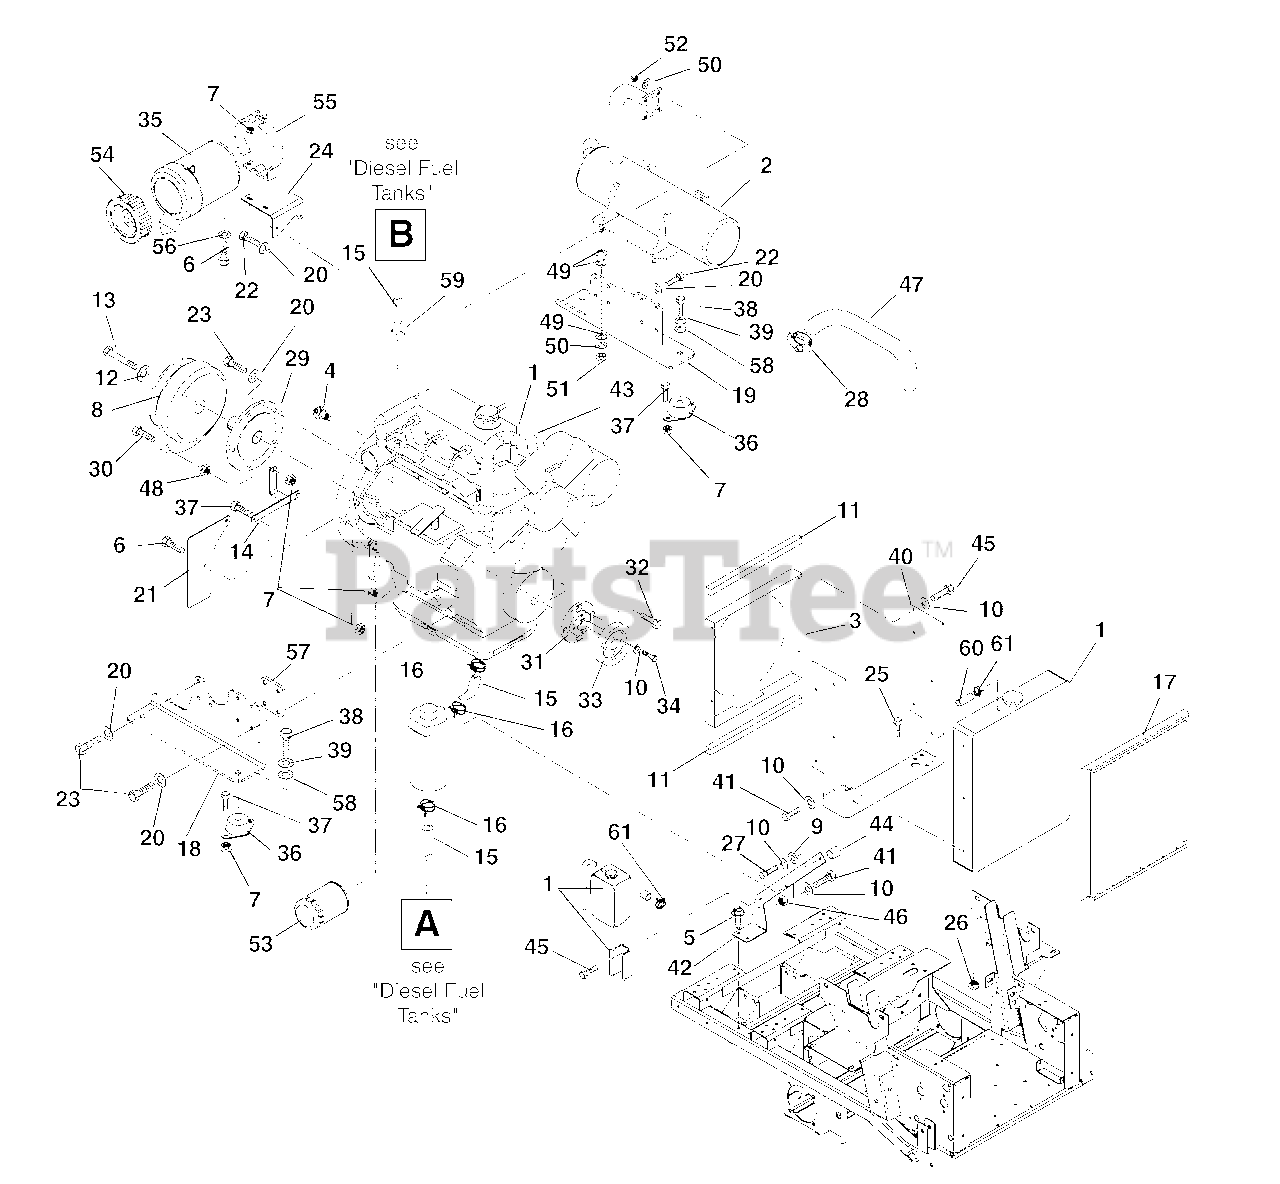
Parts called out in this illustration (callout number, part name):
1	Engine, 31HP Diesel (Daihatsu)
3	Weldment, Radiator Shroud
4	Sender, Temperature
5	Screw-Tapping .38-16 x .75 Hex Washer Head
6	Bolt-Hex .31-18 x .75 Grade 5
7	Nut-Locking-Nylon .31-18
8	Electric Clutch
9	Washer-Flat-Steel .281 x .62 x .065
10	Washer-Locking .25 x .062 Regular
11	Seal, Trim-LOK Bulk .06 Bubble
12	Washer-Locking .44 x .109
13	Bolt-Hex .44-20 x 2.50 Grade 5
14	Stabilizer, Clutch
15	Gas Line-Bulk .31" ID
16	Hose-Clamp
17	Screen, Radiator (Diesel)
18	Mount, Engine Right Hand (Diesel)
19	Mount, Engine Left Hand (Diesel)
20	Washer-Lock .31 x .078 Regular
21	Guard, Flywheel
22	Bolt-Hex M8-1.25 x 20
23	Bolt-Hex M8 x 1.25 x 25 Grade 8
24	Bracket, Air Cleaner
25	Bolt-Hex .38-16 x 1.00 Grade 5
26	Nut-Locking-Nylon .38-16
27	Bolt, Hex M6-1.00 x 45
28	Clamp, 2.25 Dia. Hose
29	Weldment, Stub Shaft
30	Bolt-Hex .31-18 x 1.50 Grade 5
31	Adapter, Sheave (Diesel)
32	Bolt, M8-1.25X25
33	Sheave 3.50
34	Bolt-Hex .25-20 x .50 Grade 5
35	Assembly, Air Cleaner
36	Mount, Engine
37	Bolt-Hex .31-18 x 1.00 Grade 5
38	Bolt-Hex .50-20 x 1.00 Grade 5
39	Washer-Locking .50 x .125 Regular
40	Bracket, Radiator Mounting
41	Bolt-Hex M6-1 x 16
42	Bracket, Overflow Mounting
43	Clamp-Hose 1.50 x .81 x 1.42
44	Spacer .328 x .76 x 1.01
45	Bolt-Hex .25-20 x .75 Grade 5
46	Nut-Locking-Nylon .250-20
47	Hose, Air Cleaner
48	Nut-Hex .31-18
49	Washer-Flat-Steel .38 x .875 x .083
50	Washer-Locking .31 x .078 Regular
51	Nut-Hex .31-18
52	Nut-Hex M8-1.25
53	Oil Filter
54	Element, Air Cleaner
55	Bracket, Air Cleaner
56	Washer-Flat-Steel .38 x .875 x .083
57	Spacer, Engine Mounting (Diesel)
58	Washer-Flat-Steel .531 x 1.06 x .095
59	Hose Clamp
60	Gas Line-Bulk .25 I.D.
61	Clamp-Hose Wire .49/.51 x .116
